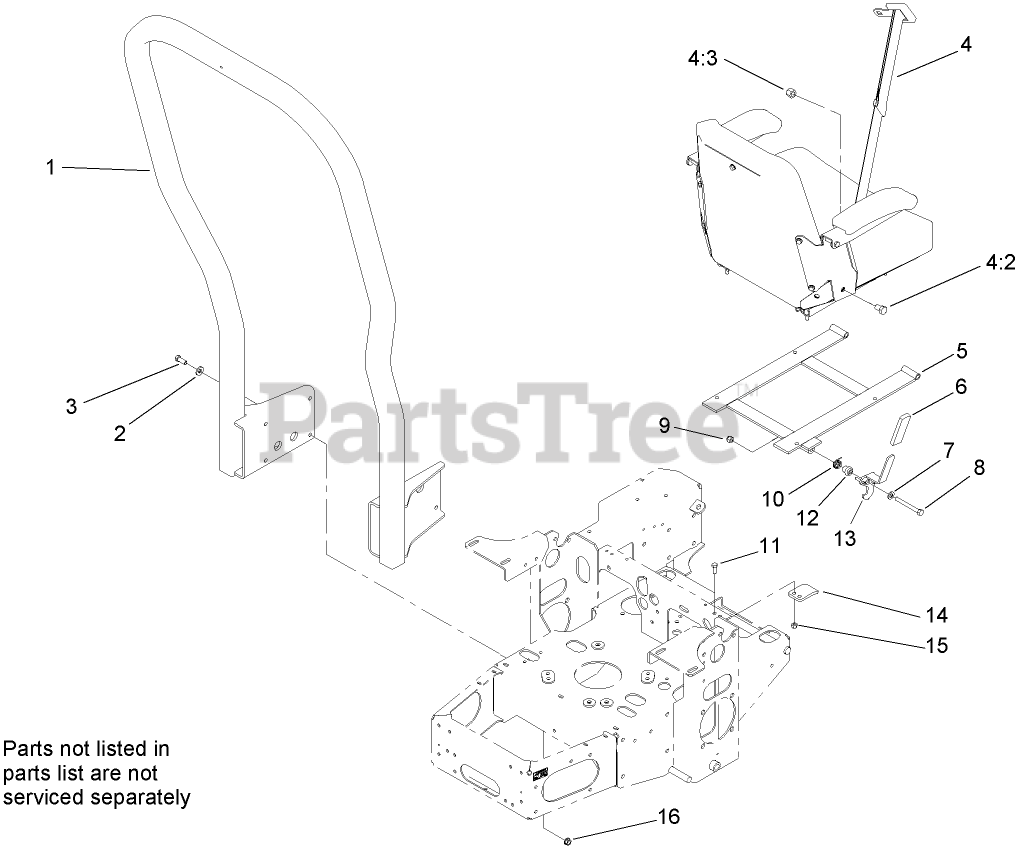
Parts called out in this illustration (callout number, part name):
2	WASHER-BELLEVILLE
3	SCREW-HH
4	SEATBELT KIT
4:2	SCREW-HH
4:3	NUT-LOCK, NI
5	SEAT SUPPORT FRAME ASM
6	GRIP-HANDLE
7	WASHER-FLAT
8	SCREW-HH
9	NUT-LOCK, NI
10	SPRING-TORSION
11	SCREW-HH
12	BUSHING-LATCH, SEAT
13	LATCH ASM
14	CATCH-LATCH, SEAT
15	NUT-LOCK, NI
16	NUT-HHF, WHIZ
